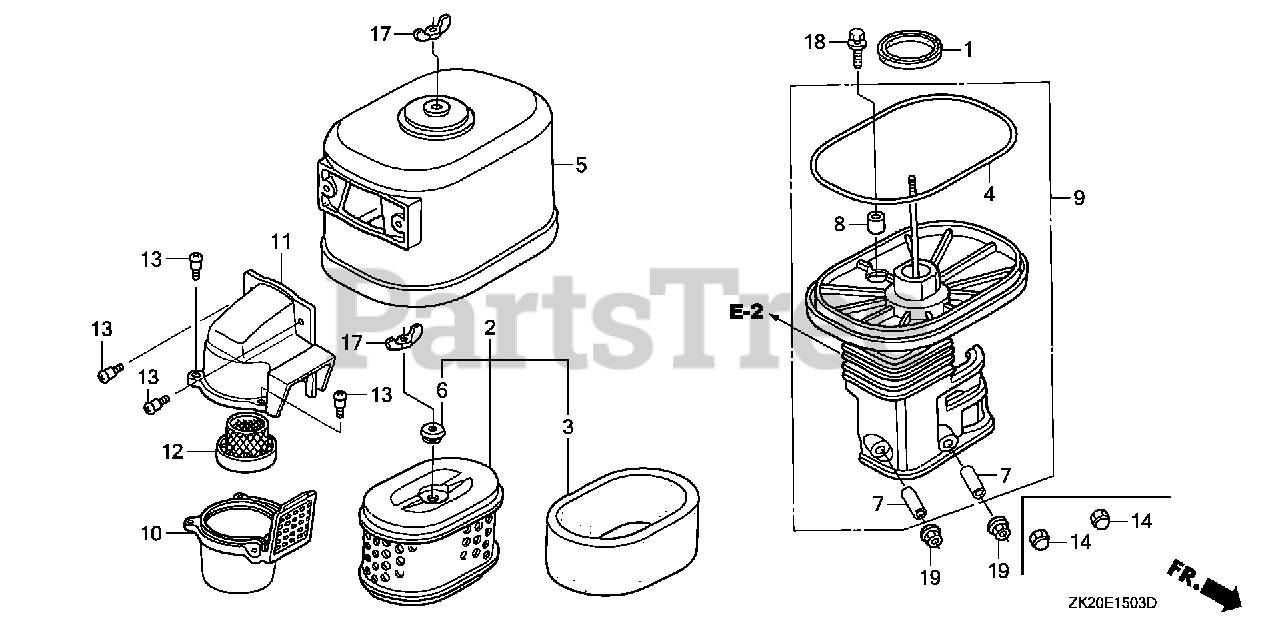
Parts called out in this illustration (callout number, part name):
1	GASKET, ELBOW
2	ELEMENT, AIR CLEANER
3	FILTER (OUTER)
4	SEAL, AIR CLEANER COVER
5	COVER, AIR CLEANER (CYCLONE)
6	GROMMET, AIR CLEANER
7	COLLAR, AIR CLEANER
8	COLLAR B, AIR CLEANER
9	ELBOW, AIR CLEANER
10	CASE, PRE AIR CLEANER
11	CAP, PRE AIR CLEANER
12	GUIDE, PRE AIR CLEANER
13	SCREW, PAN (5X16.5)
14	NUT, CAP (6MM)
17	NUT, TOOL BOX SETTING
18	BOLT-WASHER (6X20)
19	NUT, FLANGE (6MM)
